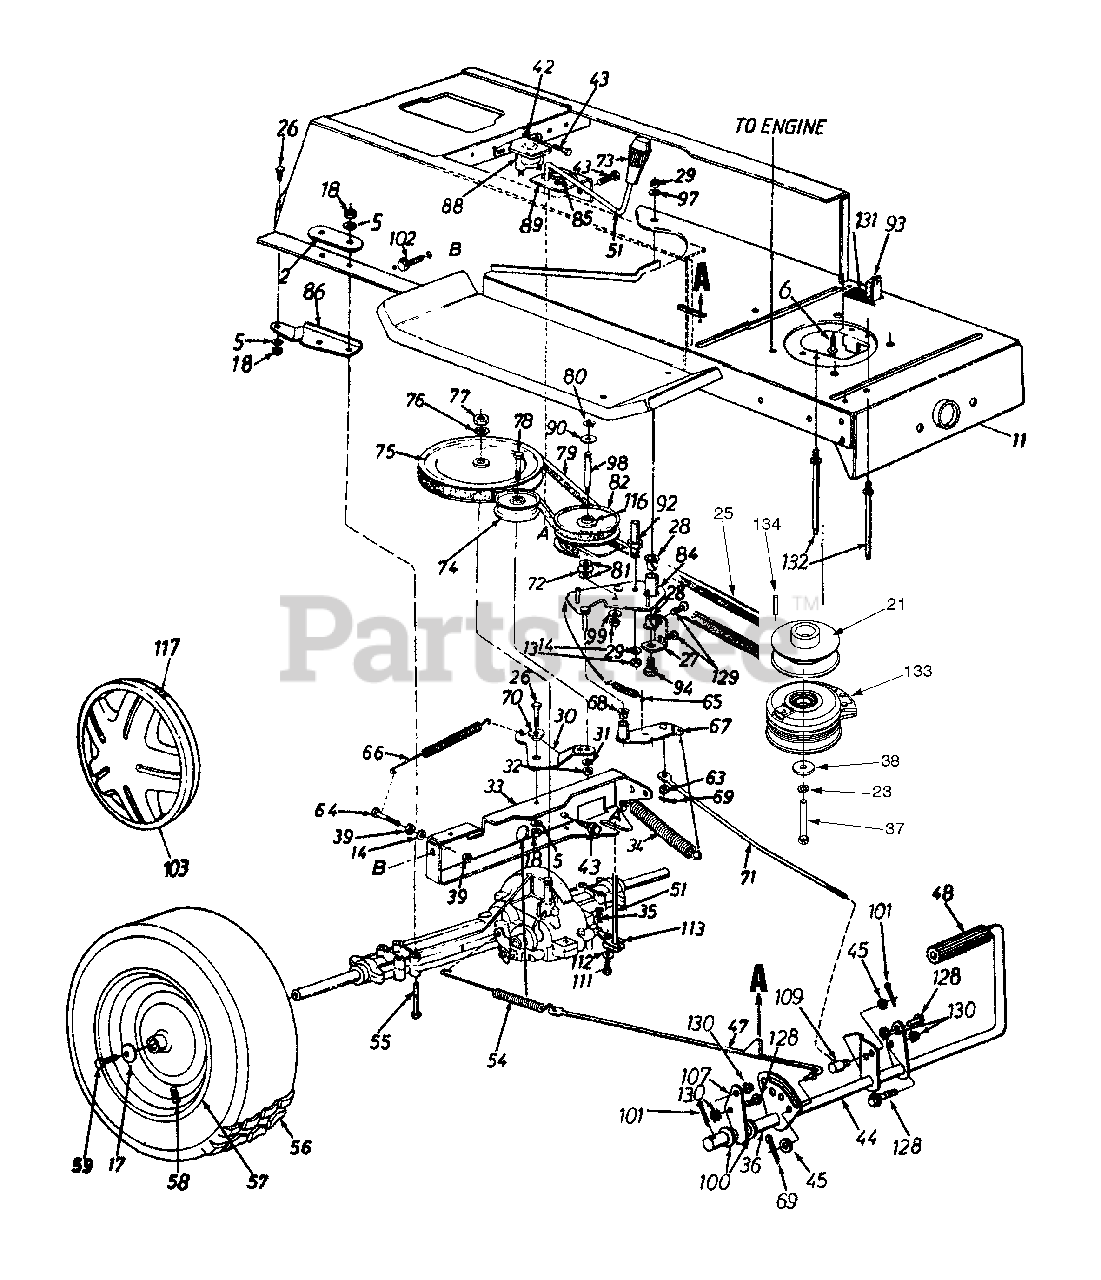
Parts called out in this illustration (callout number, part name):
5	L-Wash. 5/16" I.D.
13	Hex Nut 1/4-20 Thd.
14	L-Wash. 1/4" I.D.
17	Bell-Wash. .345" I.D. x .88"
18	Hex Nut 5/16-18 Thd.
21	Engine Pulley
23	Lock Washer 7/16
25	Variable-Speed Belt
26	Hex Bolt 5/16-18 x .75" Lg.
27	Bearing Shaft Bracket Ass'y.
28	Flanged Nyliner Brg. 5/8" I.D. x .88" Lg.
29	Hex Nut 3/8-24 Thd.
31	L-Wash. 3/8" I.D.
32	Hex Nut 3/8-24 Thd.
35	Inter. Cotter Pin
36	Spacer .63" I.D.
37	Hex Cap Screw 7/16-20 x 3.25
38	Flat Washer .45 ID x 1.5 OD
39	Hex Nut 1/4-28 Thd.
40	Hex AB-Tap Scr. 1/4" x .62" Lg.
41	Belt Guard Pin
42	Ext. L-Wash. 1/4" I.D.
43	Hex Wash. Hd. S-Tap Scr. 1/4-20 x .50"
47	Brake Rod Ass'y.
48	Foot Pad
51	Shift Lever Ass'y.
53	Ext. Spring .38" O.D. x 2.5"
54	Ext. Spring 7.33" Lg.
55	Hex Bolt 5/16-18 x 3.5" Lg.
58	Air Valve
59	Hex Bolt 5/16-24 x .75" Lg.
61	Brake Return Spring Anchor
63	Fl-Wash. .34" I.D. x .68" O.D.
64	Hex Bolt 1/4-28 x 1.25" Lg.
65	Ext. Spring
66	Ext. Spring .62" O.D. x 6.12"
68	Flanged Bearing
69	Cotter Pin 3/32" Dia.
70	Shoulder Spacer .27" Lg.
71	Speed Control Link
72	Truss Bearing .56 Dia. x 1.25"
73	Shift Knob
74	Fl-Idler Pulley 3.25" x .75"
76	Bell-Wash. .56" I.D. x 1.125"
77	Hex Jam Nut 5/16-18 Thd.
78	Hex Bolt 3/8-24 x 1.75" Lg.
79	Variable Speed Belt
80	Snap Ring .56" Dia.
82	Variable Speed Pulley Ass'y. 5" O.D.
90	Teflon Washer .565" I.D.
92	Belt Keeper 3" Lg.
93	Safety Switch (Clutch)
94	Shld. Bolt 3/8-24 x 3.12" Lg.
97	Bell-Wash. .38" I.D. x .88"
98	Shaft .56" Dia. x 3.875" Lg.
99	Bell-Wash. .39" I.D. x 1.12"
100	Fl-Wash. .64" I.D. x .94"
101	Cotter Pin 1/8" Dia. x 1.25"
102	Hex Wash. Hd. Scr. 5/16-18 x .62" Lg.
111	Hex Bolt 1/4-28 x .50" Lg.
112	Bell-Wash. .265" I.D. x .75"
113	Shift Lever Link Ass'y.
115	Fl-Wash. .385" I.D. x .62"
116	Needle Brgs.
117	Spring Clip
119	Hex Bolt 3/8-16 x 1.25" Lg.
120	Fl-Idler w/Flanges 2.75" O.D.
121	Fl-Wash. .39" I.D. x 1.12" O.D.
122	Hex Nut 3/8-16 Thd.
128	Hex Wash. TT-Tap Scr. 5/16-18 x .75" Lg.
129	Hex Wash. AB-Tap Scr. 5/16-18 x .75" Lg.
130	Hex Sems Nut 5/16-18 Thd.
131	Spring Switch
132	Belt Guard Pin
133	Electric Clutch
